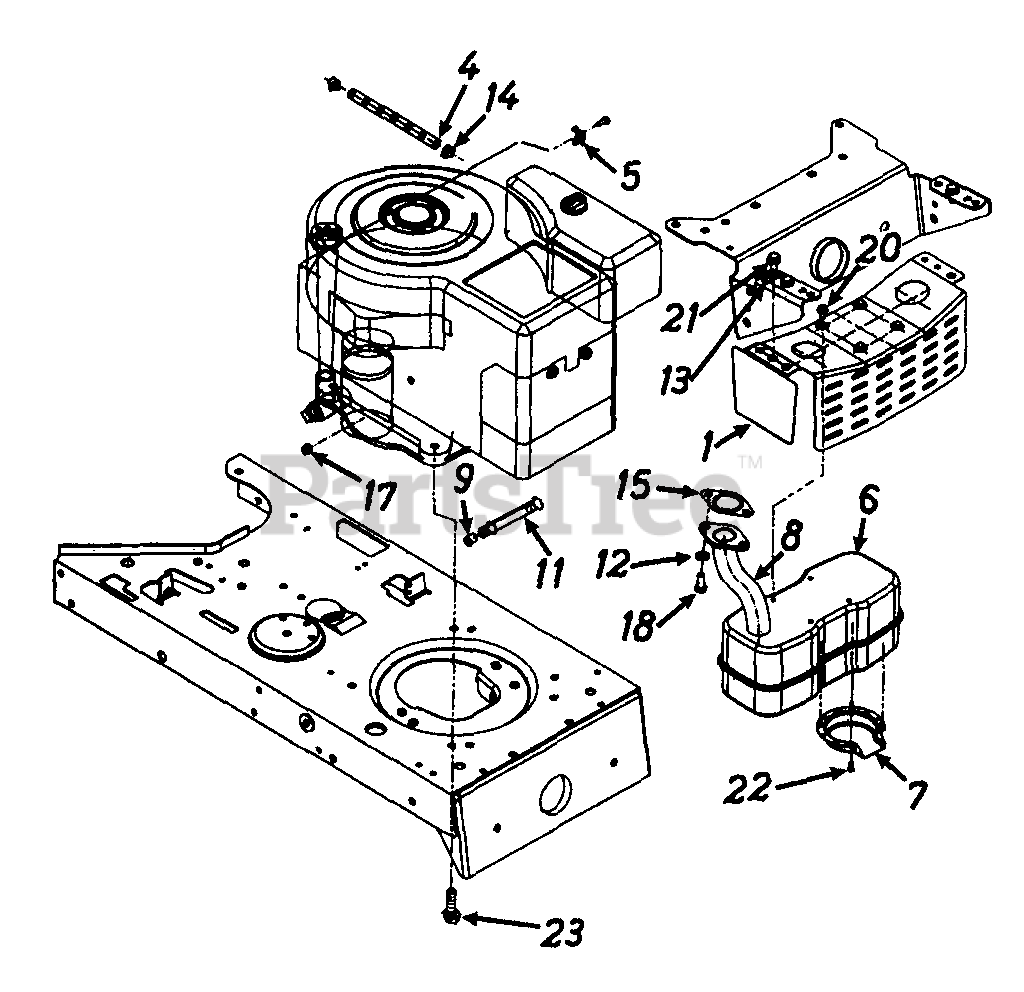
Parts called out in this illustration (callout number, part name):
1	Heat Shield Bracket
4	Fuel Line
5	Casing Clamp
6	Muffler
7	Muffler Deflector
8	Exhaust Pipe
9	Hex Pipe Cap
11	Pipe 3/8 NPT x 3.8" Lg.
12	L-Wash. 5/16" I.D.
15	Exhaust Gasket
17	Hex Sems Nut 1/4-20 Thd.
18	Socket Hd. Bolt 5/16-18 x .62" Lg.
20	Hex Wash. Hd. TT-Scr. 1/4-20 x .5" Lg.
21	Hex Wash. Hd. TT-Scr. 5/16-18 x .62" Lg.
22	Hex Bolt #8-32 x .38" Lg.
23	Hex Wash. Hd. TT-Scr. 3/8-16 x 1.25" Lg.
